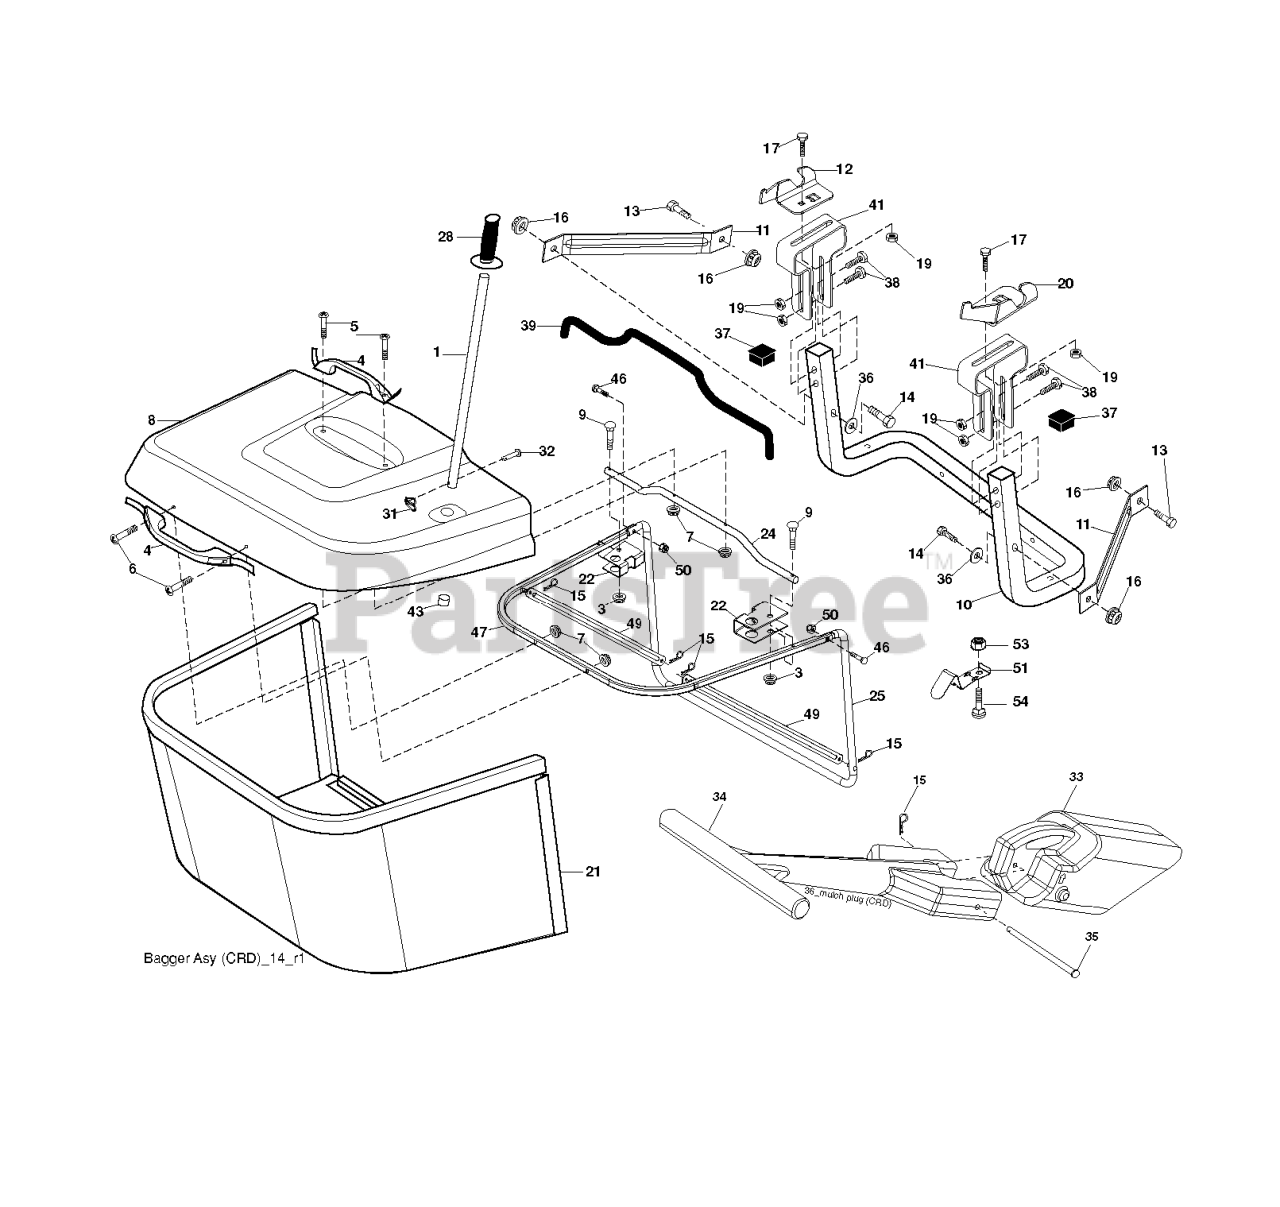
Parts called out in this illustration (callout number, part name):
1	TUBE HANDLE
3	NUT T
4	HANDLE.BAGGER.W/LVRS.BLK.CRD
5	SCREW.PAN.HEAD
6	REPL BY 532 75 00-29
8	COVER.PNT.BGR.CRD.WSLOTS.MS668
9	Bolt Carriage 1/4-20 x 2.25d x Gr.5
10	TUBE
11	BRACKET.SUPPORT.UPPER.BAG.CRD
12	BRKT PIVOT
14	BOLT-HEX EAK
15	RETAINER-SPRNG RB
16	NUT LOCK FLG 3/8-16 UNC
17	RP BOLT 5/16-18 X3/4 ZN/YEL GR
19	NUT LOCK HEX FLANGE 5/16-18
20	BRKT.PIVOT.RH.CRD
21	BAGGER.ASM.CRD.2007
22	BRKT.SIDE.BAG.CRD
24	TUBE.PIVOT.BAG.CRD.BLACK
25	PIPE
28	GRIP.HANDLE.BLACK
31	RETAINER CLIP
32	RIVET,DRILLED
33	MULCH PLUG, CTH150
34	HANDLE.MULCHER.92.CRD (2 2)
36	WASHER
37	Plug Support Bagger CRD
38	BOLT.5/16-18X2.5
39	SEAL.BAGGER.CRD
41	BRKT.VERT.ADJ.BAGGER.CRD
43	PLUG, TUBING END
46	BOLT.CARRIAGE.5/16-18
47	PIPE
49	ROD
50	NUT.71038.31-18.HEX.NYLOCK
51	LATCH
53	NUT
54	BOLT
